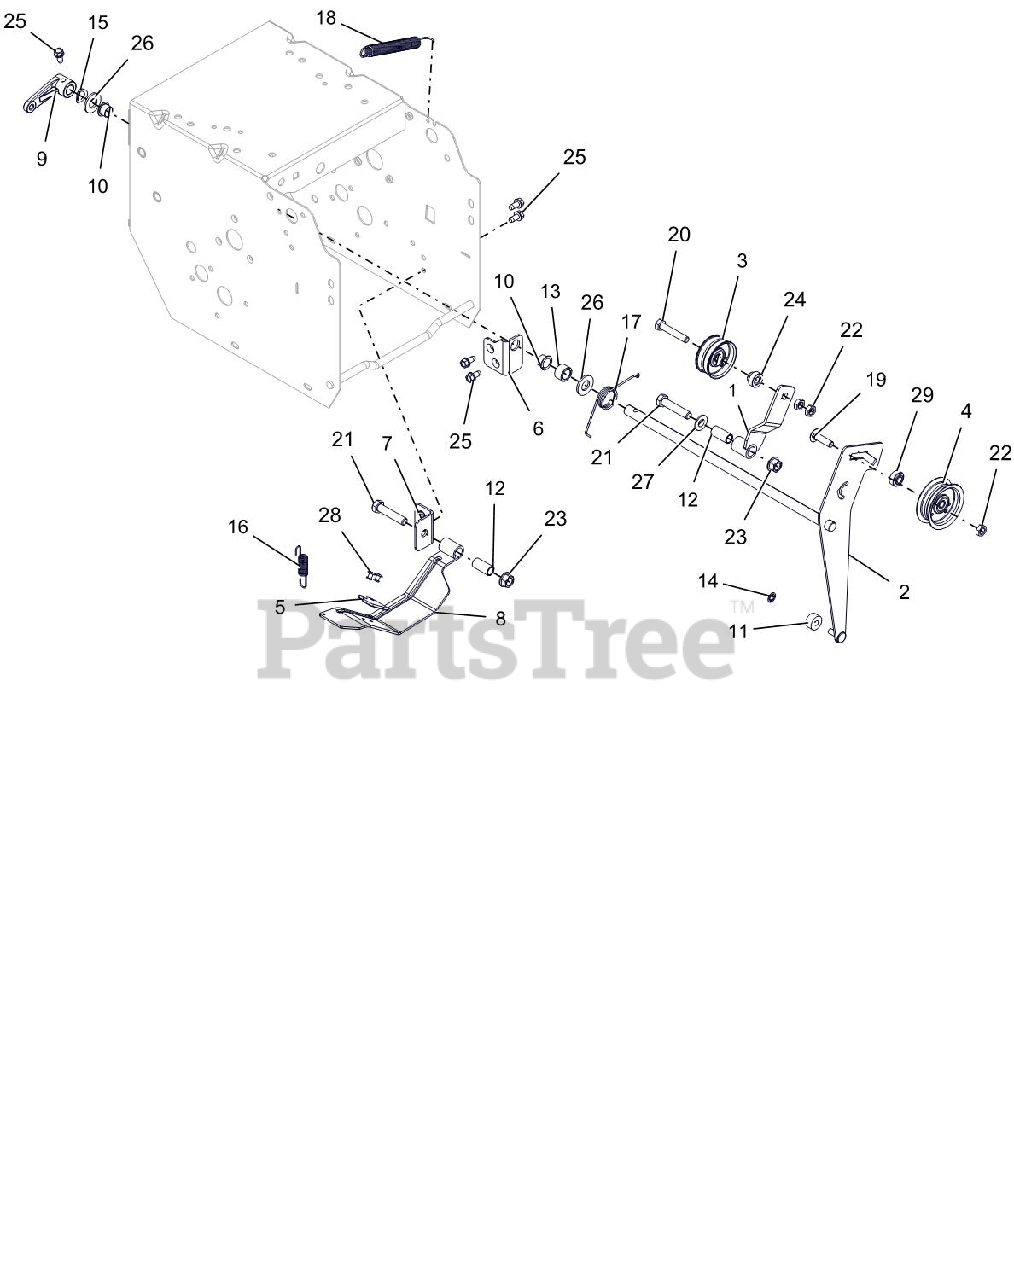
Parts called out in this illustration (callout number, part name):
1	ARM, TRACTION IDLER
2	WELDMENT, ATTACHMENT IDLER ARM
3	IDLER, FLAT - 1.875"
4	IDLER, FLAT - 2.00"
5	PAD, BRAKE
6	BRACKET, MOUNT - IDLER ARM
7	BRACKET, MOUNT - BRAKE
8	BRAKE ARM W/PAD
9	ARM, CLUTCH - ATTACHMENT
10	BUSHING, POLYLINER-.50 SPLIT
11	BSHG,SLV .265 X .625 X .375
12	BSHG-SLV .385X.500X1.045
13	BSHG-SLV .510X.751X.475
14	RG-RTNG-EXT .250X.010
15	WSHR-WAVE .50X.75X.015 .13FRHT
16	SPRING-EXT .437 X .438 X 2.64
17	SG-TORS .075 X .955
18	SPRING, EXTENSION
19	BLT-RDHDSQSHNK.31-18X1.13 G5YZ
20	@BLT-HEX .31-18X1.75 GR5 YWZC
21	@BLT-HEX .38-16X1.75 GR5 YWZC
22	@NUT-LK-CTR-JAM .31-18 YWZC
23	@NUT-LK-TOP-FLG .38-16 YWZC
24	SPCR, BRG .315X.500X.481X.281
25	SCR-TAP .25-20X.50 HWH TR YWZ
26	@WSHR-FL-STL.531X1.06X.095YWZC
27	@WSHR-FL-STL.406X.812X.065 YWZ
28	RVT-POP .187 YZ
29	SPCR, BRG .315X.500X.358X.281
